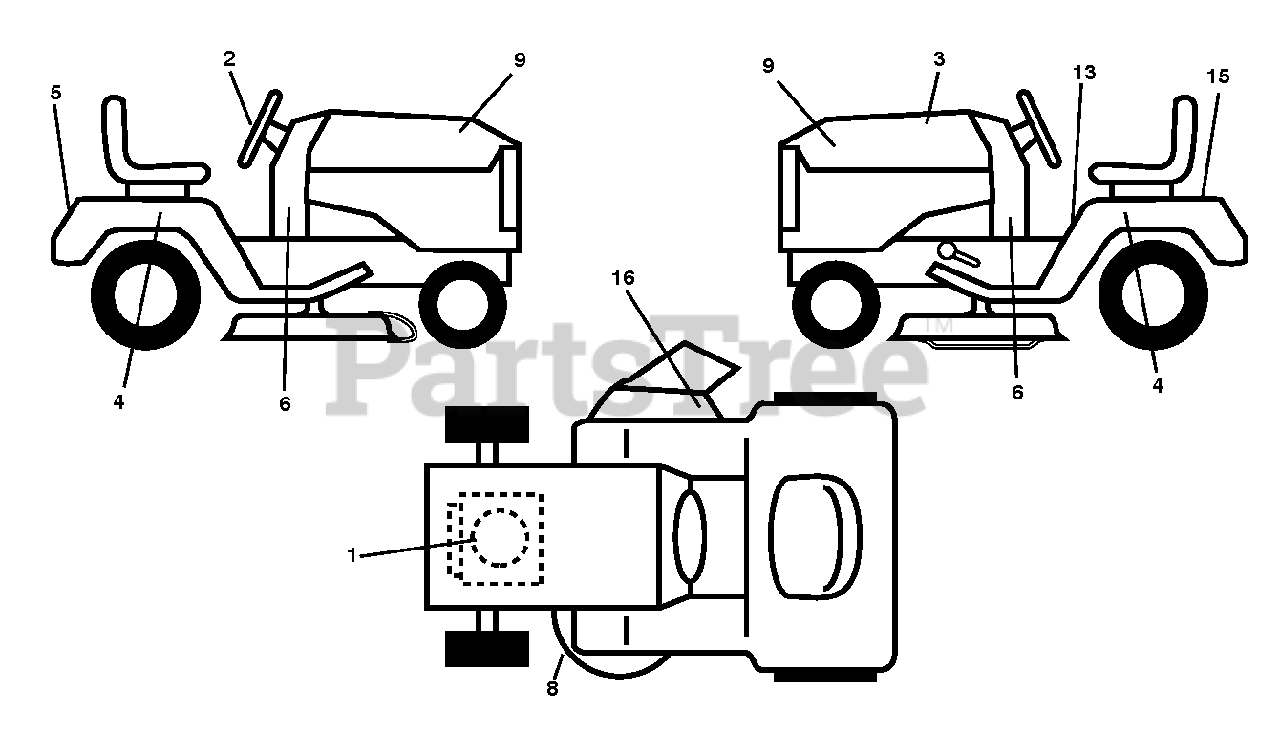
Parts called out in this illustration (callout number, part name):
1	DECAL.ENG.BS.5HP.PB.278978
2	DECAL.WHEEL.STRG.STDHRS.POULAN
3	DECAL.RPL.PMST.42C.BS.175.STL
4	DECAL.FEND.RH/LH.SET.6S.POULAN
5	DECAL.FEND.POULAN.2010
6	DECAL.DASH.LWR.17.5/42.POULAN
8	DECAL V BELT SCHEMATIC
9	DECAL.HOOD.ALPHA.RH/LH.POULAN
13	Fender Warning Decal, English
15	DECAL BTRY SYMBOLS
16	DECAL.WARN.KEEP.HAND.AWAY
